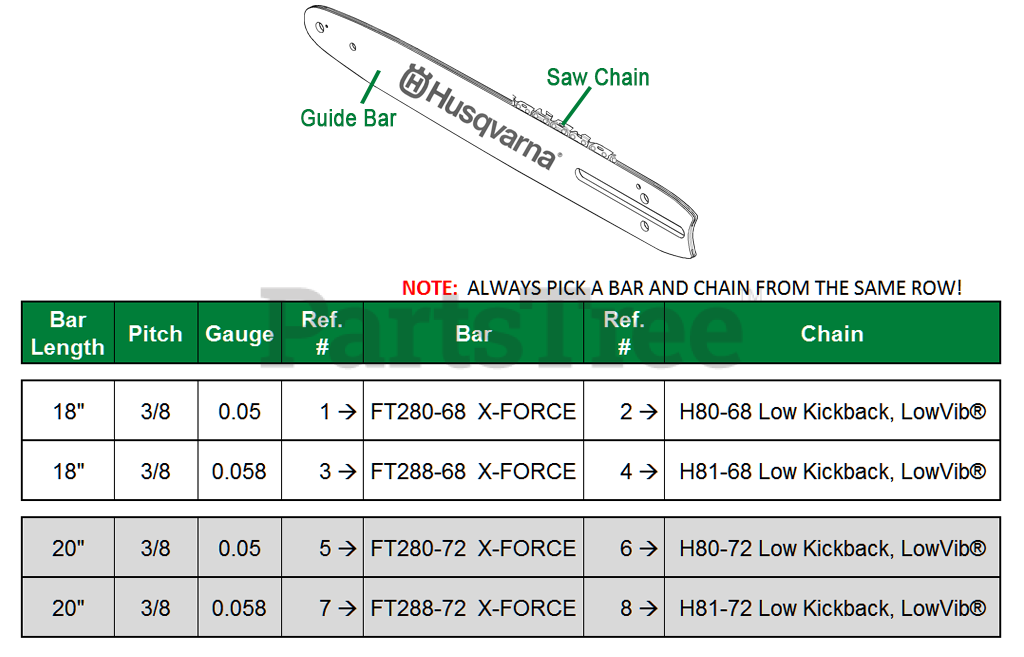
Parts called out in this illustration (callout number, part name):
1	Laminate Bar FT280-68 X-Force
2	H80-68 Low Kickback, LowVib� Chain
3	Laminate Bar FT288-68 X-Force
4	H81-68 Low Kickback, LowVib� Chain
5	Laminate Bar FT280-72 X-Force
6	H80-72 Low Kickback, LowVib� Chain
7	Laminate Bar FT288-72 X-Force
8	H81-72 Low Kickback, LowVib� Chain
